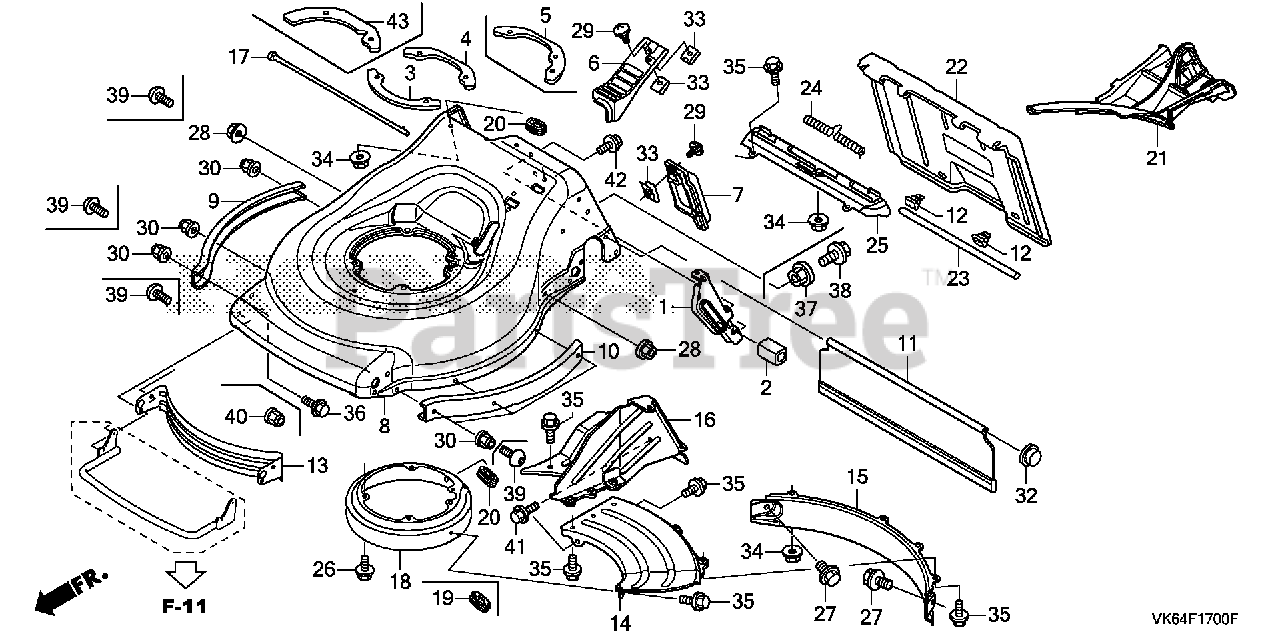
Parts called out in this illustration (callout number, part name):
1	GUIDE, TRANSMISSION MOUNT
2	SLIDER, TRANSMISSION
3	SPACER, ENGINE (A)
4	SPACER, ENGINE (B)
6	COVER, DRIVESHAFT
7	COVER, RR.
8	HOUSING, CUTTER *NH190M* (VINTAGE GRAY METALLIC)
9	GUARD, R. HOUSING
10	GUARD, L. HOUSING
11	SHIELD, RR.
12	STOPPER, DISCHARGE GUARD
13	SCROLL, FR.
14	SCROLL, RR. (UPPER)
15	SCROLL, RR. (LOWER)
16	SCROLL, DISCHARGE
17	SHAFT, RR. SHIELD
18	COVER, ROTO-STOP
20	GROMMET, CABLE
21	STUFFING *NH105* (MAT BLACK)
22	GUARD, DISCHARGE
23	SHAFT, DISCHARGE GUARD
24	SPRING, GUARD RETURN
25	PLATE, GRASS BAG
26	BOLT, ENGINE SETTING
27	BOLT, SPECIAL
28	NUT, SELF-LOCK (8MM)
28	NUT, FLANGE (8MM)
29	BOLT, CHUTE SETTING
32	NUT, PUSH (6.35MM)
33	NUT, CLIP (6MM)
34	NUT, FLANGE (6MM)
35	BOLT, FLANGE (6X12) Use up to Engine SN 1543277.
39	SCREW, HEX. SOCKET BUTTON (6X12)
40	NUT, NYLON RING (6MM)
41	BOLT, FLANGE (6X10)
42	BOLT, FLANGE (6X12) Use up to Engine SN 1543277.
43	SPACER B, ENG
